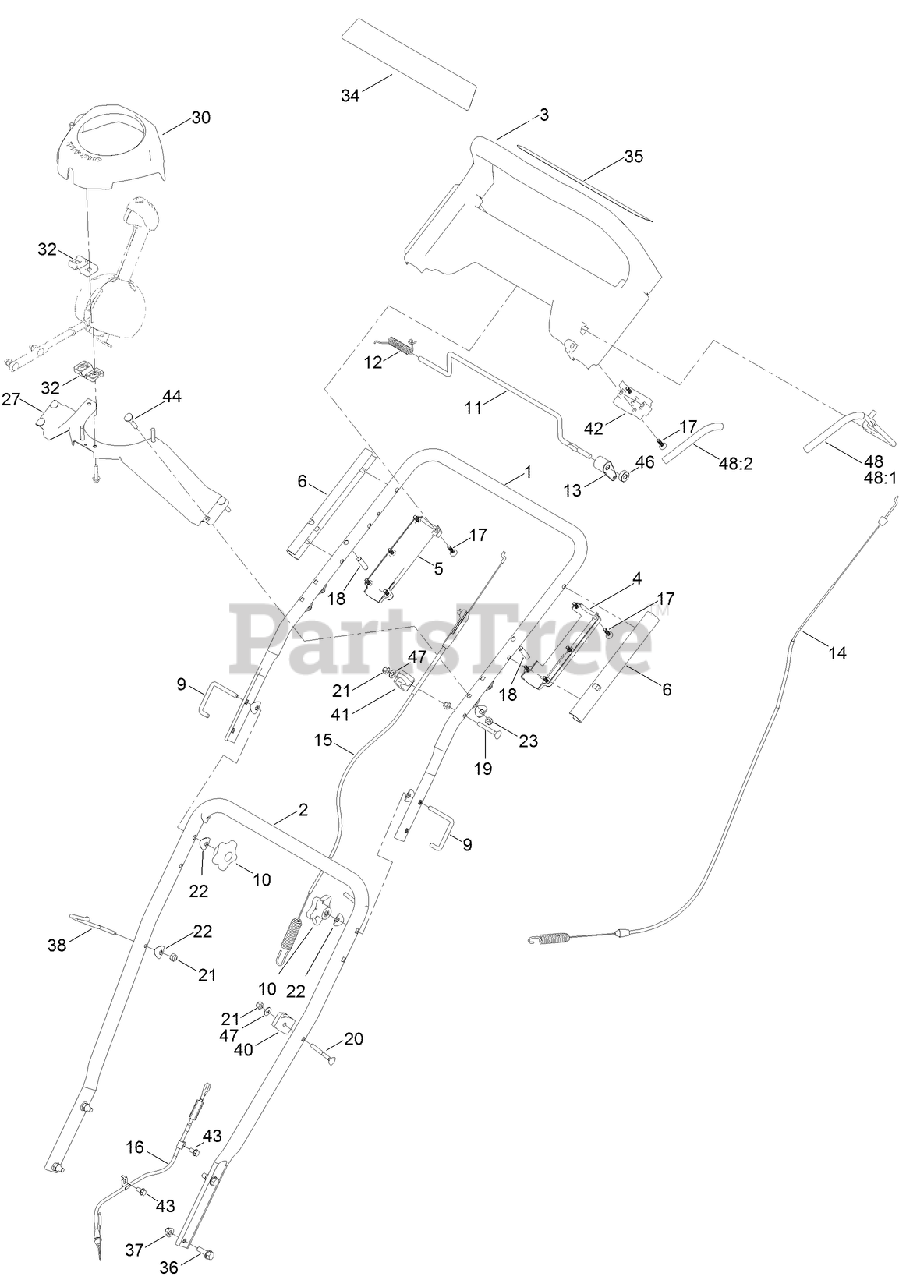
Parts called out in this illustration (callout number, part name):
1	HANDLE-UPPER
2	HANDLE-LOWER
3	HANDLE
4	HANDLE-BOTTOM, LH
5	HANDLE-BOTTOM, RH
6	SLEEVE HANDLE
9	LOCK-HANDLE
10	KNOB-HANDLE
11	BAR-CONTROL, TRACTION
12	SPRING-TORSION
13	LEVER-TRACTION
14	CABLE-TRANSMISSION
15	CABLE-ROTOR, UPPER
16	CABLE-ROTOR, LOWER
18	PIN-DOWEL
19	SCREW
20	SCREW-HANDLE
21	NUT-LOCK, NI
22	WASHER
23	NUT-LOCK, NI
27	BRACKET-CHUTE, CONTROL
30	COVER TOP
32	SUPPORT-ROD
34	DECAL-DISPLAY
35	DECAL-CONTROL, PANEL
36	SCREW-HHF
37	NUT-HF, NI
38	GUIDE-ROPE
40	ANCHOR-CABLE, UPPER
41	CABLE-GUIDE
42	BAIL-MOUNT
43	SCREW-HWH
44	SCREW-HANDLE
46	SPACER
47	WASHER-FLAT
48	BAIL ASM
48:1	BAIL-AUGER
48:2	COVER-BAIL
